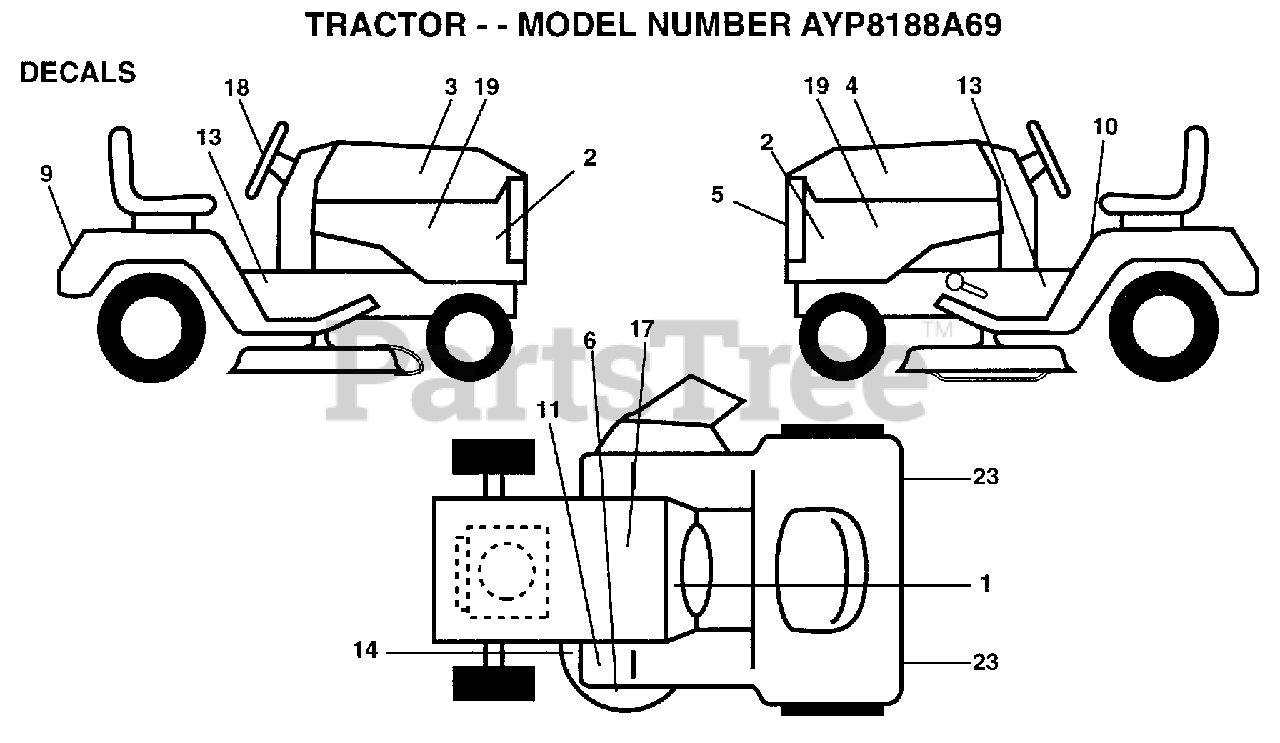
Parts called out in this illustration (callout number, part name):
1	DECAL.DASH.INST.
2	NAMEPLATE.HD.WIZA
3	DECAL.HD.RH.WIZRD
4	DECAL.HD.LH.WIZRD
5	DECAL.GRILLE.WIZ+
6	DECAL DECK WIZ +
10	DECAL
13	DECAL CHASSIS
14	"DECAL.V.BELT.44"""
17	DECAL.BTRY.DANGER
18	DECAL INS STG WHL
19	DECAL.PNL.SD.VANG
23	REFLECTOR-TAIL YT
